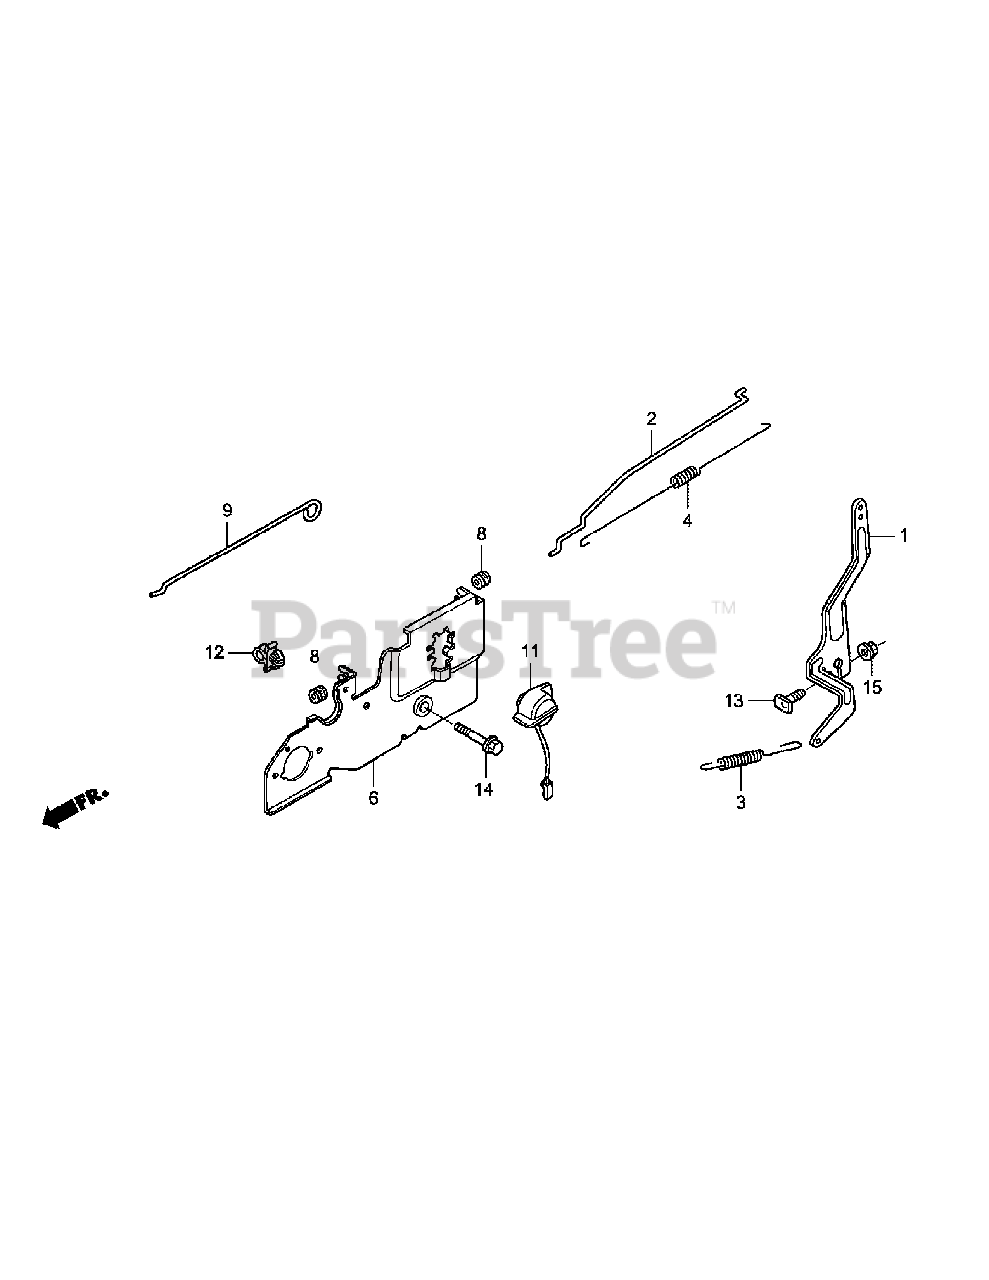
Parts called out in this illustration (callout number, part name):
1	Control Assembly
2	Governor Arm
3	Governor Rod
4	Governor Spring
5	Throttle Return Spring
6	Control Base
7	Choke Rod Grommet
9	Petcock Assembly
10	Engine Stop Switch Assembly
11	Wire Holder
12	Flange Bolt, 6 x 12
13	Governor Arm Bolt
14	Flange Bolt, 6 x 32
17	Screw, 5 x 12
18	Flange Nut, 6mm
